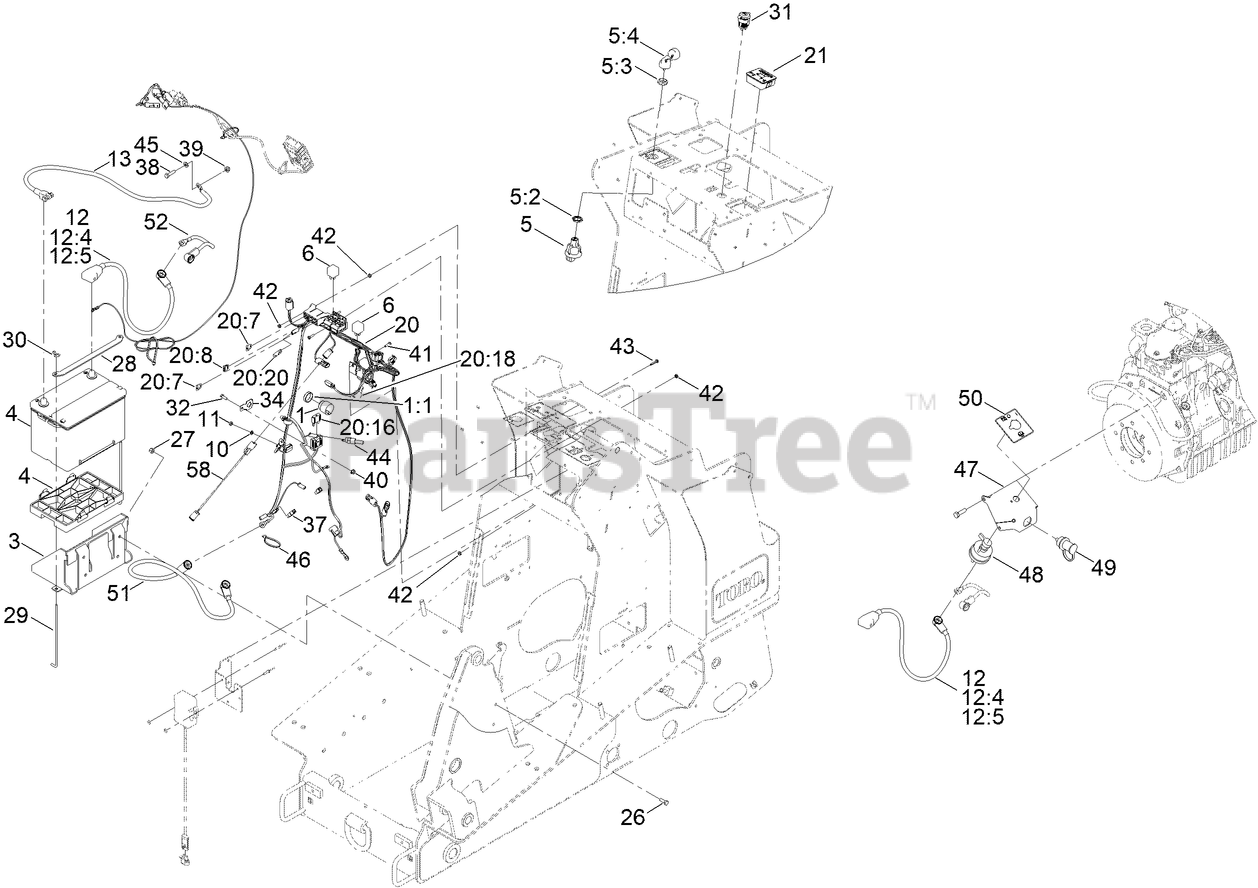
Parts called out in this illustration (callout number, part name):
1	AUDIO ALARM ASM
1:1	NUT-PLASTIC, KNURLED
3	TRAY-BATTERY
4	BATTERY
5	IGNITION SWITCH ASM
5:2	NUT-HEX
5:3	NUT-FACE
5:4	SET-KEY, IGNITION
10	WASHER-LOCK, SPRING
11	NUT-HEX
12	CABLE-BATTERY, POS ASM
12:4	BOLT-BATTERY CLAMP, 5/16-18 UNC
12:5	NUT-CLAMP, BATTERY
13	CABLE-NEGATIVE
20	HARNESS-WIRE
20:7	FUSE-BLADE, 10 AMP
20:8	FUSE-BLADE, 15 AMP
20:16	FUSE-BLADE, 50 AMP
20:20	CAP-PLUG
21	MODULE-HOUR METER
26	SCREW-HH
27	NUT-LOCK, NI
28	STRAP-HOLD DOWN, BATTERY
29	ROD-HOLD DOWN, BATTERY
30	NUT-WING
31	RECEPTACLE-12V
32	SCREW-HH
34	CLIP-FUSE
37	HARNESS-LINK, FUSIBLE
38	SCREW-HH
39	NUT-HF, NI
40	NUT-HF
41	SCREW-HWH
42	NUT-KEPS
43	SCREW-HWHTF
44	SWITCH-TEMP
45	WASHER-PLAIN
46	TIE-CABLE
47	MOUNT-REMOTE TERMINAL
48	SWITCH-DISCONNECT, MASTER
49	STUD-JUMPER, POSITIVE
50	DECAL-BATTERY DISCONNECT
51	CABLE-BATTERY, POSITIVE
52	CABLE-BATTERY, POSITIVE
58	HARNESS-WIRE
